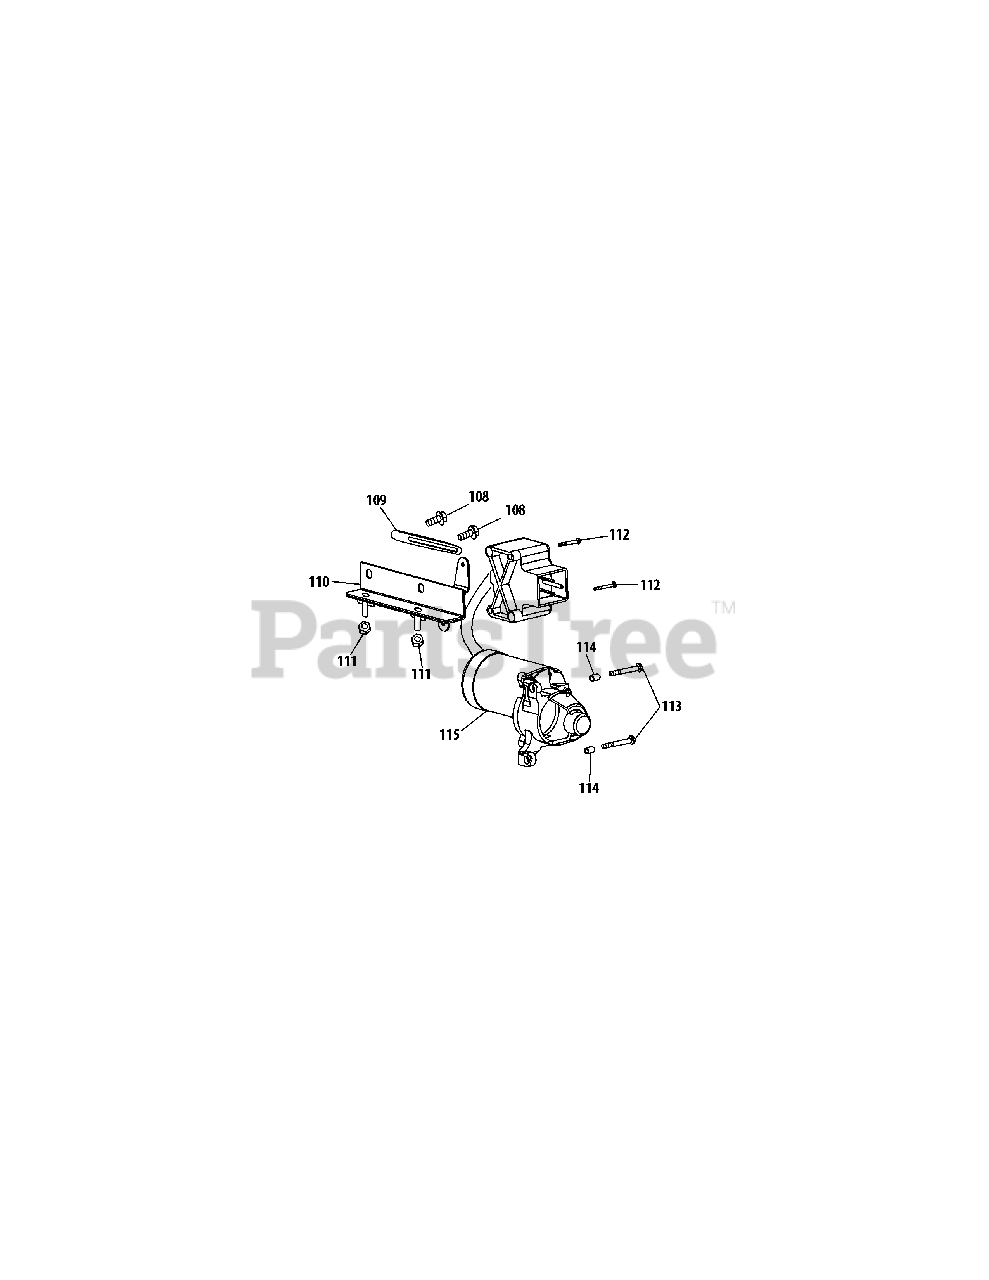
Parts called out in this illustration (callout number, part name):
108	Bolt M6×10
109	Flexible Clamp
110	Switch Housing Mounting Brkt
111	Nut, M6
112	Bolt M4×55
113	Bolt M6×32
114	Dowel Pin 8×8
115	Electric Starter
